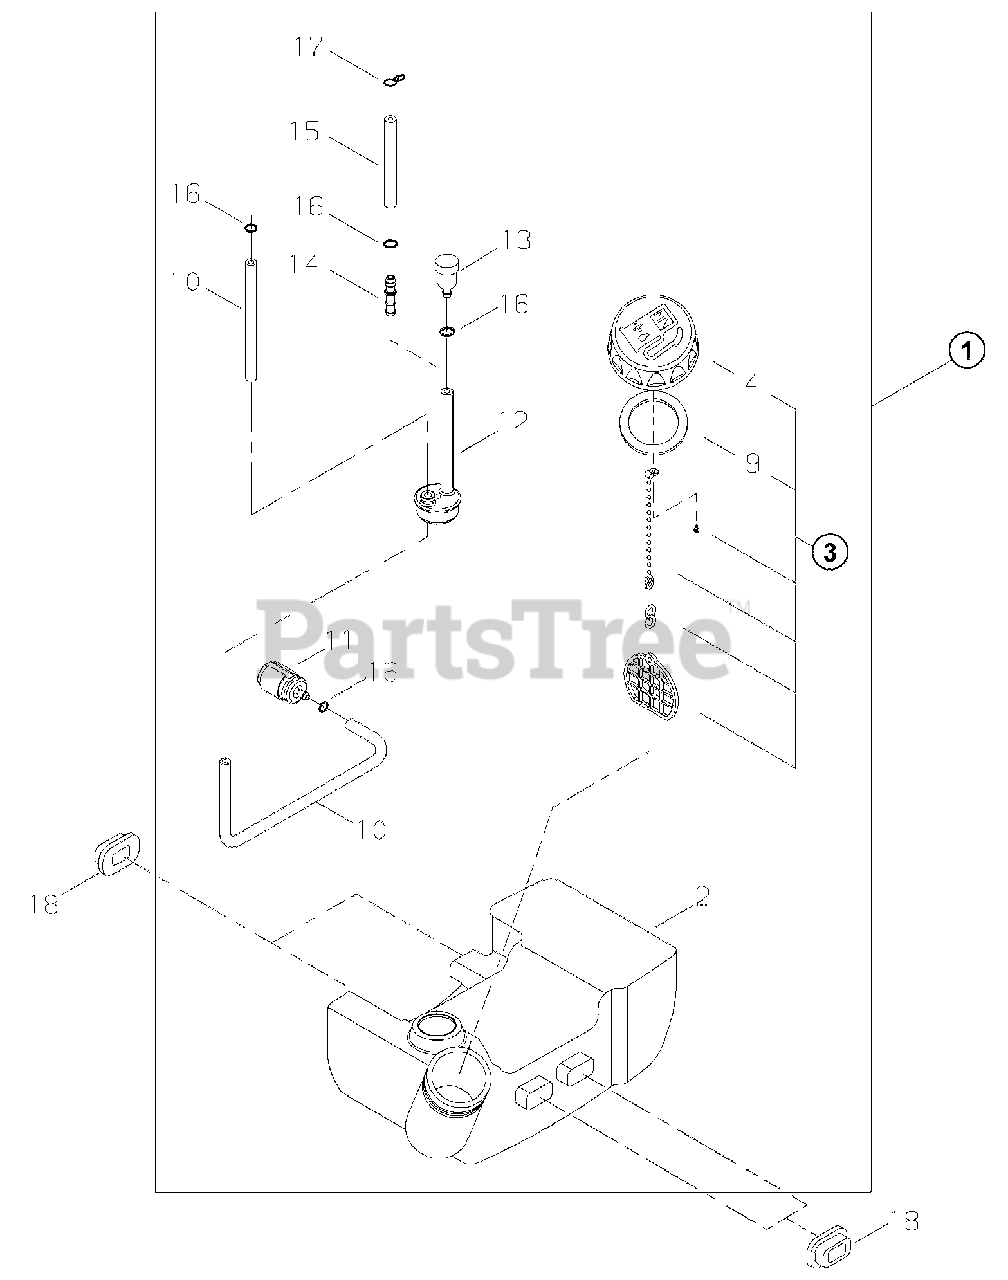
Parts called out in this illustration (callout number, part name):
1	TANK ASSY, FUEL
2	TANK, FUEL
3	CAP ASSY, FUEL
4	CAP, FUEL
9	GASKET, FUEL CAP
10	PIPE, FUEL 3.3×6×160
11	FILTER, FUEL 125-528
12	GROMMET
13	VENT ASSY
14	CONNECTOR, PIPE
15	PIPE
16	CLIP Ø6
17	CLIP, SPRING Ø5.2
18	CUSHION, FUEL TANK
